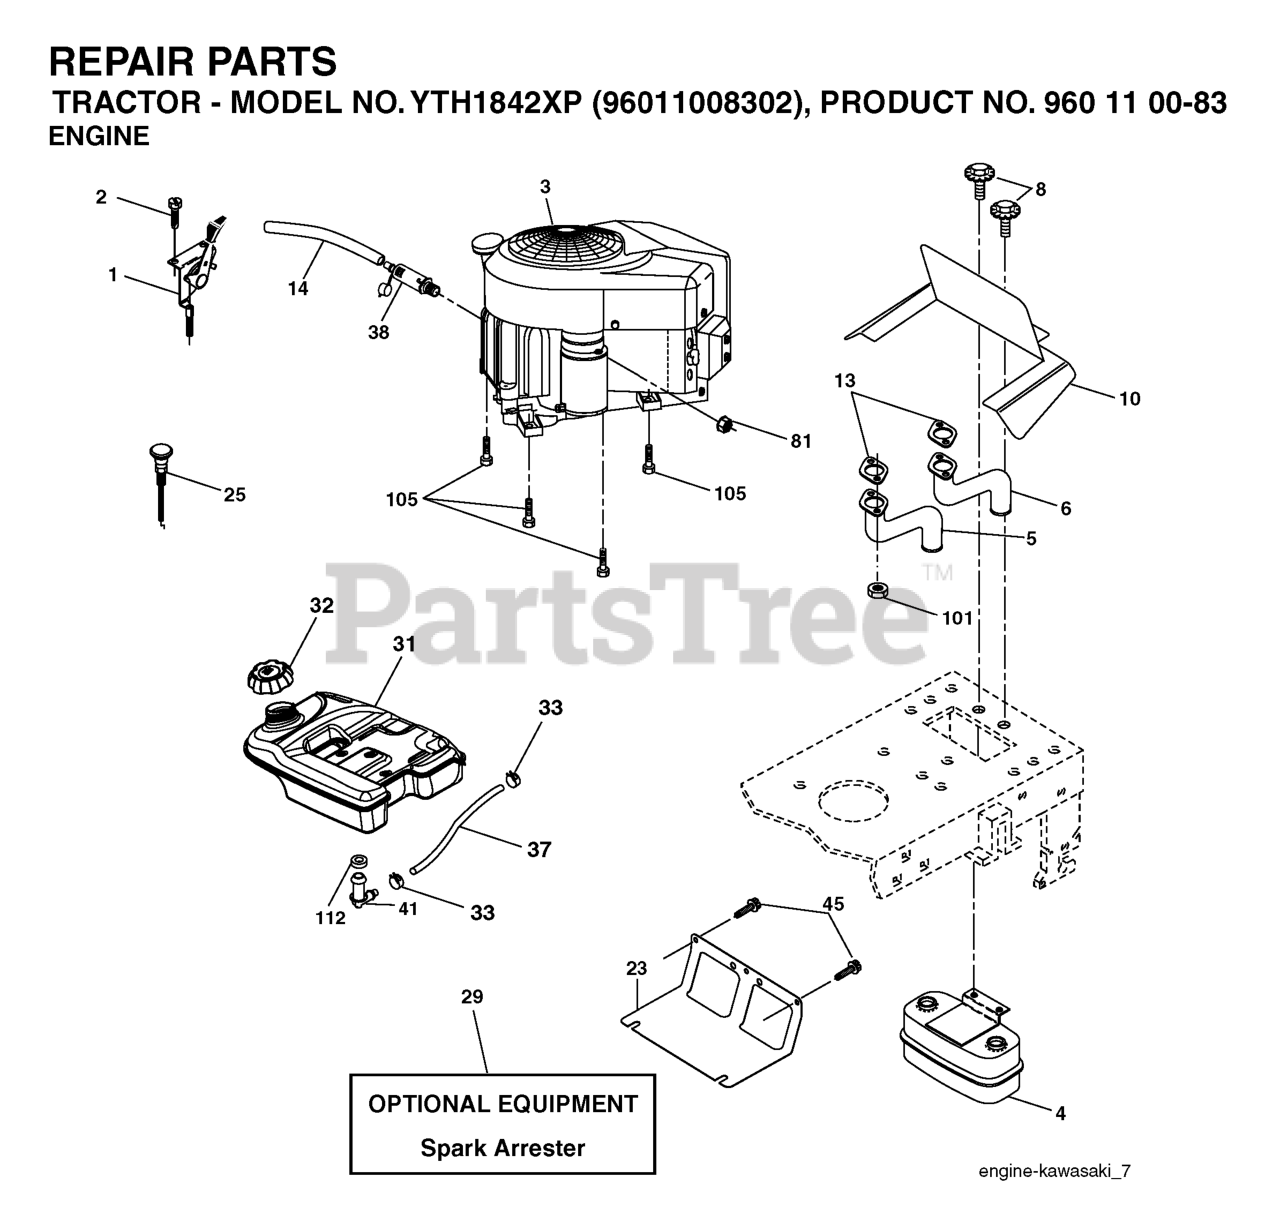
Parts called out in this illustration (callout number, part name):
1	AUGER.BLADE.SS.SNOW
2	SUPPORT.BEARING.SINGLE.STAGE.B
3	BEARING.BALL.MANDREL
4	RETAINING RING LT
6	WELDMENT.AUGER.SINGLE.STAGE.BL
7	PLATE.CENTER.BLADE.BLACK
8	PIN.ROLL.3/16 X 1-1/4
10	BOLT.CARRIAGE.1/4-20 X 7/8
11	NUT.HEX.FLANGE.1/4
12	NUT
